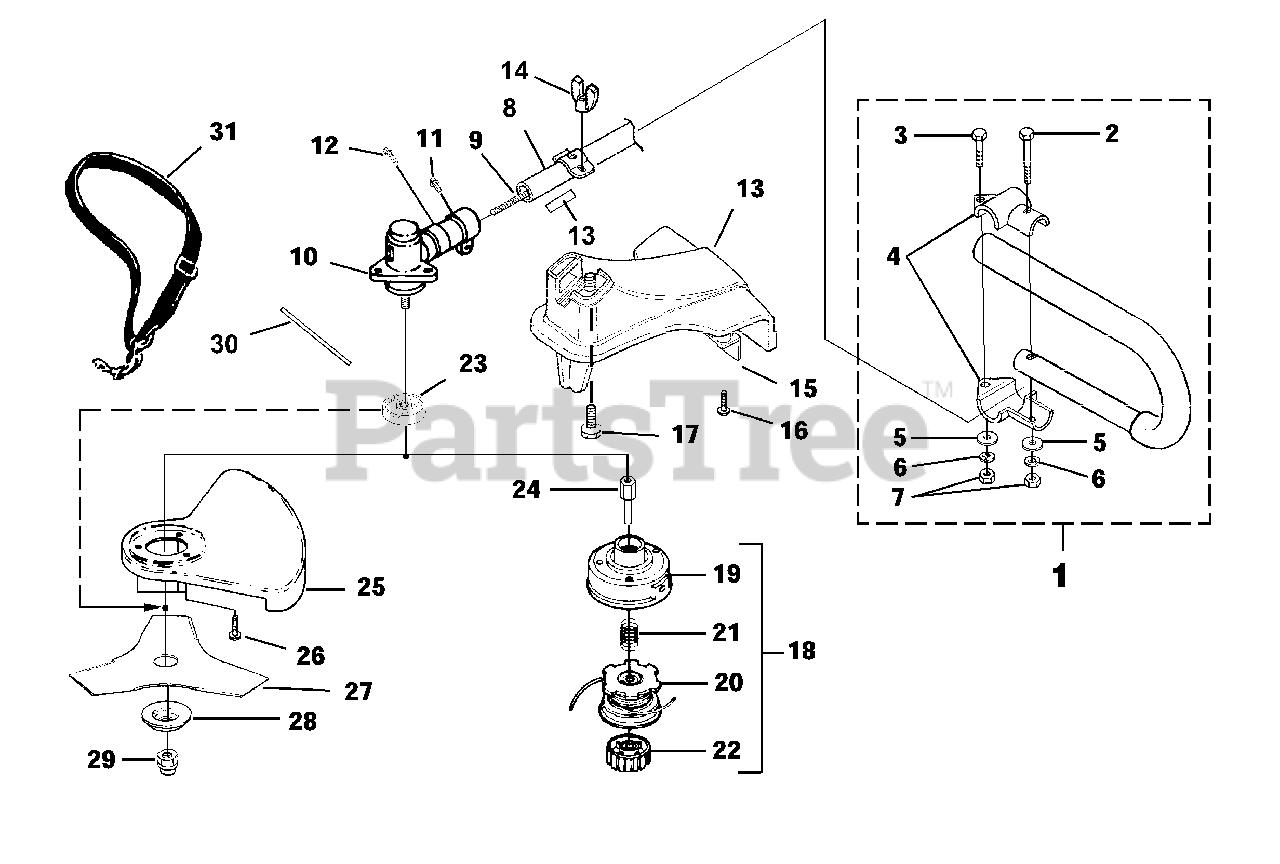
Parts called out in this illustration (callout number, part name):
1	HANDLE("J")
2	SCREW-Hex Hd. (1/4-20 X 1 1/2")
3	SCREW-Hex Hd. (1/4-20 X 1")
4	CLAMP-Handle Bar
5	WASHER-Flat (1/4")
6	WASHER-Lock (1/4")
7	NUT-Hex (1/4-20)
8	DRIVESHAFT HOUSING
9	FLEXSHAFT
10	GEAR HEAD
11	Screw, Cap Hd. (1/4-20 X 7/8")
12	Screw-Hex Hd. (10-24 x 1/2")
13	GRASS DEFLECTOR KIT
14	WING NUT
15	BLADE-Cut-Off
16	SCREW, Thread Form. (10-24 X 3/4")
17	SCREW-Square Head
18	STRINGHEAD-Complete (.080")
19	HOUSING & EYELET (Dual Line)
20	SPOOL & STRING (.080")
21	SPRING-Compression
22	RETAINER-Spool (L.H. Thread, Red)
23	WASHER-Flanged
24	ADAPTER-Shaft
25	BLADE GUARD
26	SCREW
27	BLADE-Tri-Arc(TM)
28	WASHER-Cupped (Lower)
29	NUT-Hex (L.H.)
30	TOOL-Holding Pin
31	HARNESS
